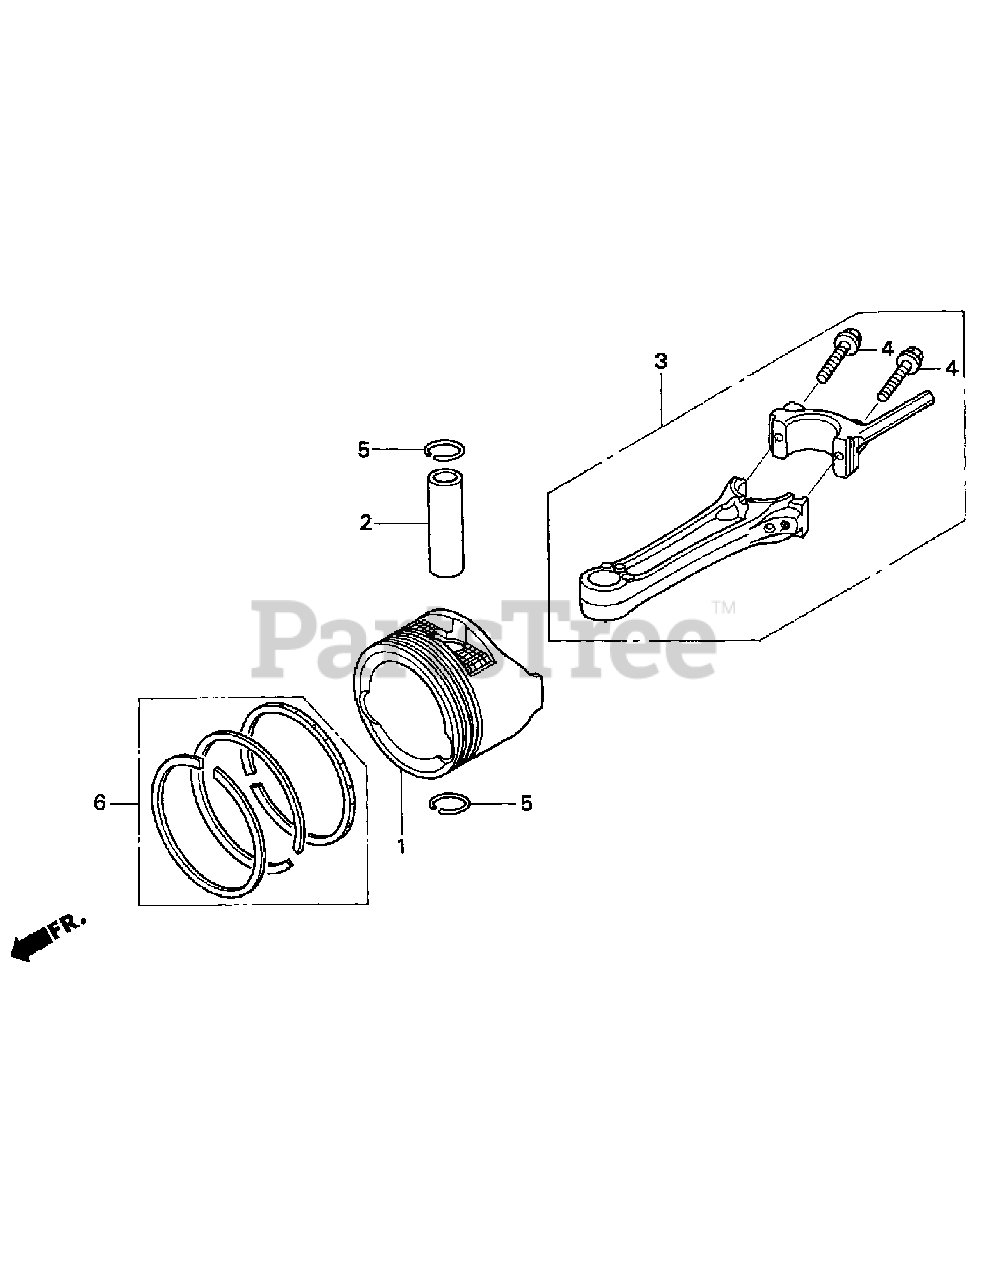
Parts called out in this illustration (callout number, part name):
2	PIN, PISTON
3	ROD ASSY., CONNECTING
4	BOLT, CONNECTING ROD
5	CLIP, PISTON PIN (13MM)
6	RING SET, PISTON (RIKEN)
